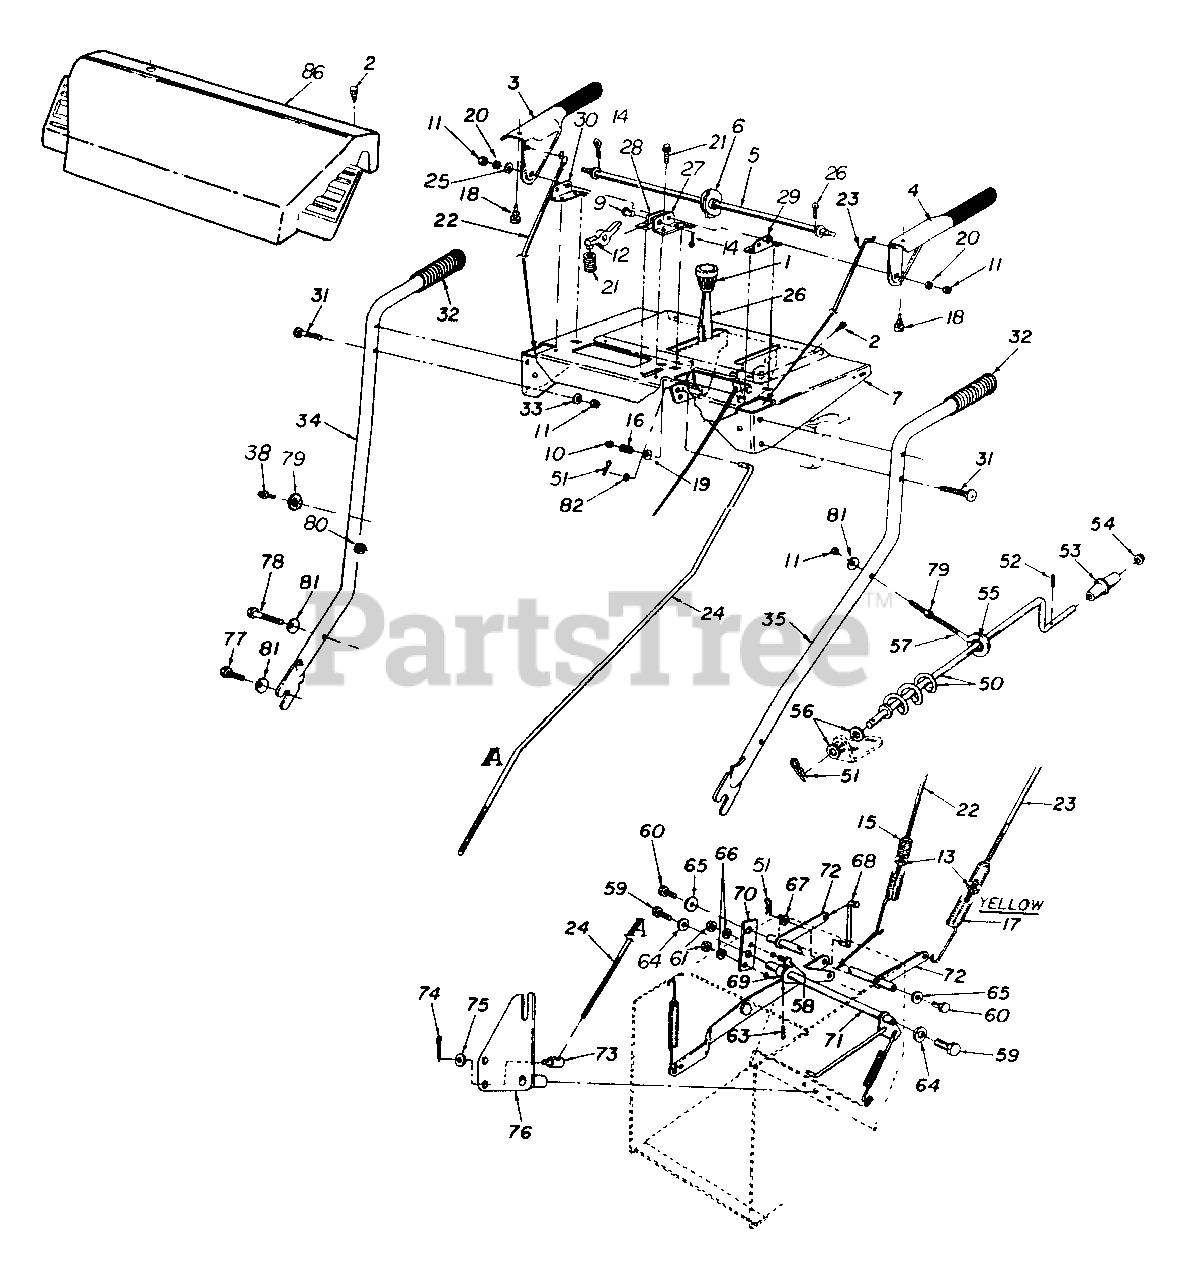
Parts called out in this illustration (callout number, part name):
1	Ball Knob
2	Truss Mach. B-Tap Scr. #10 x .50
3	Engagement Handle R.H. - Black
4	Engagement Handle L.H. - Black
5	Cam Rod
6	Clutch Lock Cam
7	Handle Panel Support Ass'y.
9	Clevis Pin .81 Dia. x 1.0" Lg.
10	Hex Nut 3/8-24
11	Hex Nut 5/16-18
12	Cam Lock Paul
13	Hex Ins. Lock Nut 1/4-20
14	Cotter Pin 3/32 Dia. x 1.00" Lg.
15	Extension Spring
16	Compression Spring .38" I.D. x .88" Lg.
17	Extension Spring .75" O.D. x .5" Lg.
18	Rubber Bumper
19	Bell-Wash .400" I.D. x .88" O.D. x .06
20	L-Wash. 5/16" I.D.
21	Wave Spring Washer
22	Lockout Cable x 28" Lg.
23	Lockout Cable x 25" Lg.
24	Shift Rod 34.25" Lg.
25	Washer (Special)
26	Shift Lever
27	L.H. Handle Support Brkt. 5/8"
28	R.H. Handle Support Brkt. 5/8"
29	L.H. Handle Support Brkt. 3/8"
30	R.H. Handle Support Brkt. 3/8"
31	Carriage Bolt 5/16-18 x 1.75" Lg.
32	Grip
33	Bell-Wash .400" I.D. x .88" O.p. x .06"
52	Serrated Pin
54	Cap Speed Nut 3/8" Rod
55	Grommet
56	Flat Wash. 385" I D. x .62" O.D. x .06
57	Eyebolt Chute Crank
58	Hex Screw 1/4-20 x 62"
59	Hex L-Bolt 5/16-18 x .62"
60	Hex Scr 1/4-20 x 50 w/Patch
61	Hex Nut 1/4-20
63	Roll Pin 3/16 x 1.25
64	Flat Wash .344" I.D. x .875" 0 D.
65	Flat Wash 25" I.D. x .93" O.D. x 125
66	L-Wash. 1/4" I.D
67	Fl-Wash. 281" I D x .62" 0 D. x .051
68	"L" Rod .25" Dia x 4 70" Lg
69	Drive Clutch Brkt 627 R.H Ass'y.
70	Pivot Bracket .63 Hole
71	Drive Clutch Shaft Ass'y
72	Pivot Cross Shaft Ass'y.
73	Adjustment Ferrule
74	Cotter P(n 3/32 x .75
75	Fl-Wash. 344" t D. x .625" O.D. x .063
78	Hex Screw 3/8-16 x 1.75
81	Bell-Wash. 400" I.D. x .88" O.D. x .06"
82	Fl-Wash .344" I D. x .625" O.D. x .063"
86	Handle Panel
